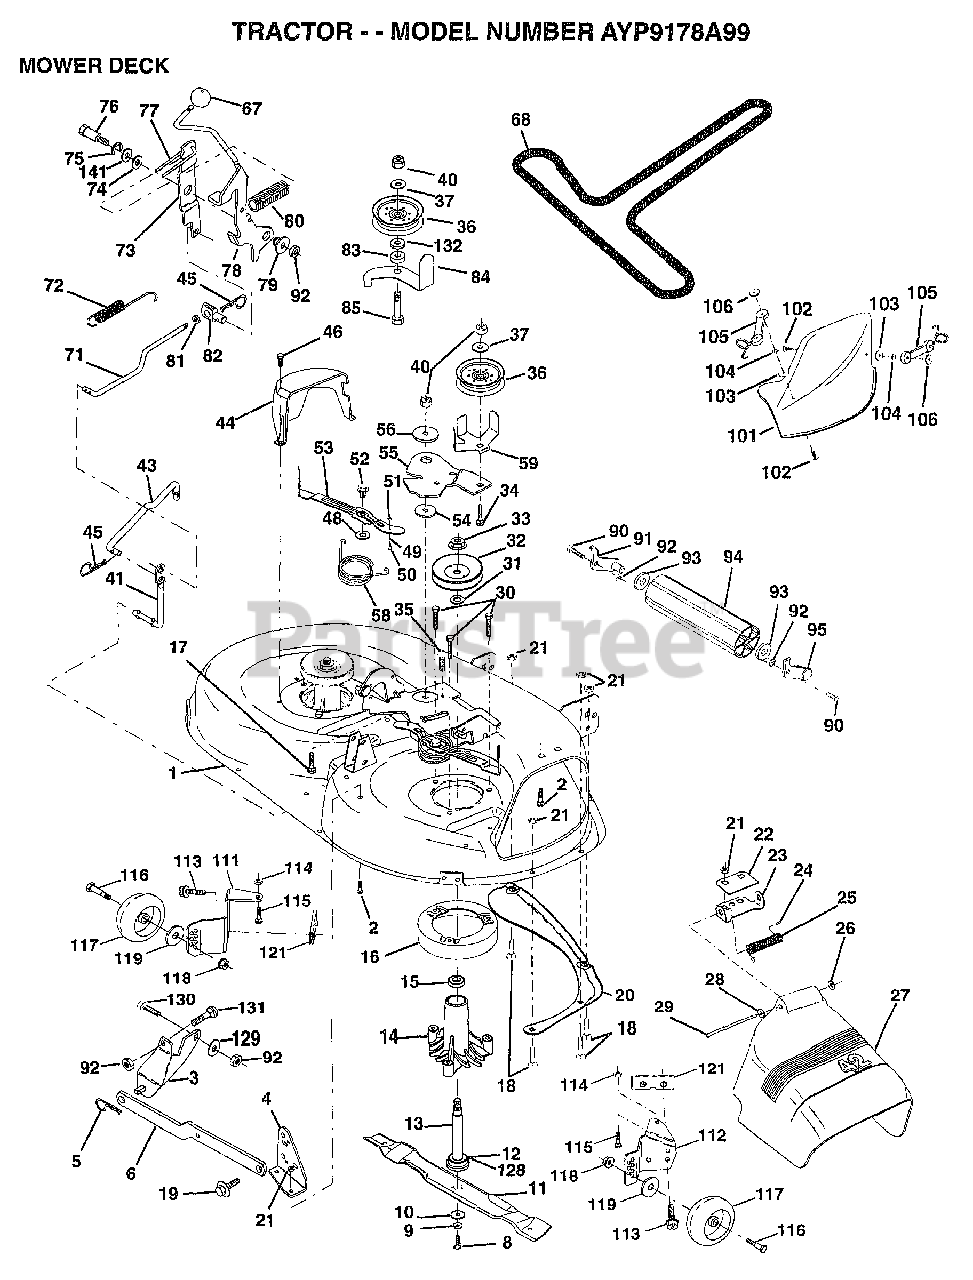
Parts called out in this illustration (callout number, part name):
1	"HOUSING ASSY.42"""
2	BOLT
3	BRKT ASM SWAY BAR
4	BRKT DECK SW BAR
8	BLADE BOLT
10	WASHER.HARD.BLADE
11	"BLADE.42"" MULCHER"
12	BEARING.BALL
14	HSG ASM MANDREL
15	BEARING
16	STRIPPER RND MWR
17	BOLT RDHD 3/8-16
18	BOLT
19	BOLT SHD 5/16-18
20	BAFFLE VORTEX 42
23	DEFLECTOR BRKT
24	CAP-SLEEVE LT
25	SPRING TORSION
26	NUT PUSH M
27	DEFLECTOR.SHIELD
28	WASHER
29	HINGE ROD
30	"SCREW-THD ROLL,WA"
31	WASHER
32	PULLEY.MANDREL.42
34	BOLT
35	XMAS TREE FASTNER
36	FLAT IDLER PULLEY
37	WASHER
41	PIVOT ROD
43	ROD CLUTCH W/NIBS
44	GUARD MAND LH BLK
45	RETAINER M
46	SCREW.1/4-20X5/8
48	HARD SMALL WASHER
49	ROLLER ASM-CAM
50	SHOULDER BOLT
51	LOCKNUT
52	BOLT.SHLD.5/16-18
53	BRAKE PAD ARM ASM
54	HARDENED WASHER
55	ARM-IDLER
56	SPACER RETAINER
58	SPRING TORSN BRAK
59	GUARD IDLER TUV
67	KNOB.RD.7/16-14
68	BELT.V.T-PATH
71	ROD CLUTCH 38/42
72	RETURN SPRING
73	CLUTCH ARM SECOND
74	WASHER
75	RING
76	SHOULDER BOLT
77	SPRING KEEPER
78	LEVER.ASM.CLUTCH
79	BUSHING
80	SPRING.CLUTCH.MWR
81	NUT
82	TRUNION ADJ
83	WASHER
84	"KEEPER-BELT,FIXED"
85	BOLT
90	BOLT
92	NUT
93	WASHER
101	"COVER.MULCH.42"""
102	SCREW
103	WASHER #10
104	LOCKWASHER
105	LATCH ASSY.BAGGER
106	WELDNUT
111	BRACKET.GWHL.LH.
112	BRACKET.GWHL.RH.
113	SCREW
116	BOLT.SHOULDER
117	WHEEL GAGE DONUT
118	LOCKNUT
119	WASHER
121	BRACKET.EXTRD.GWL
128	WASHER.FELT.
129	WASHER
130	BOLT
132	WASHER GT
141	WASHER .T
